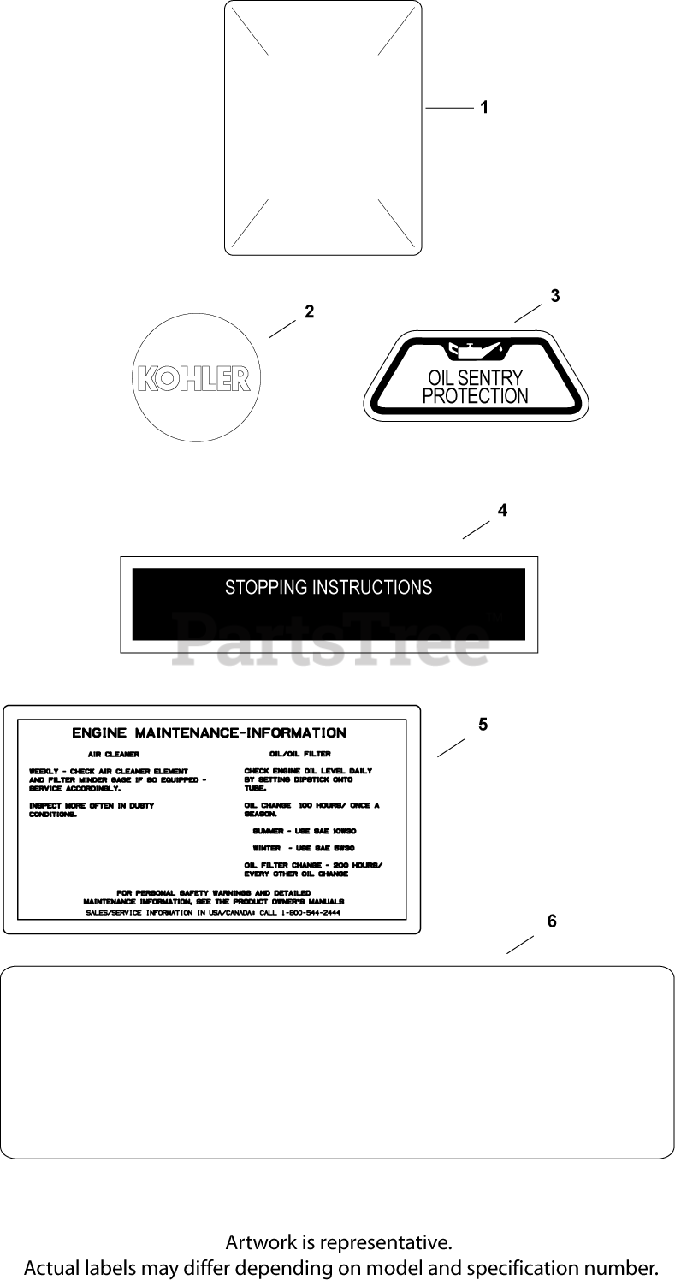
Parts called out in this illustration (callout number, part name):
1	DECAL, CLEAR LAMINATE USE 25 113 70-S
2	LABEL, (ROUND KOHLER GOLD)-USE 24 113 18
3	DECAL, OIL SENTRY - (#DSC)
4	DECAL, STOPPING INSTRUCTION
5	DECAL, AIR CLEANER - (#DSC)
6	DECAL, 23 HP - (#24113216S)
